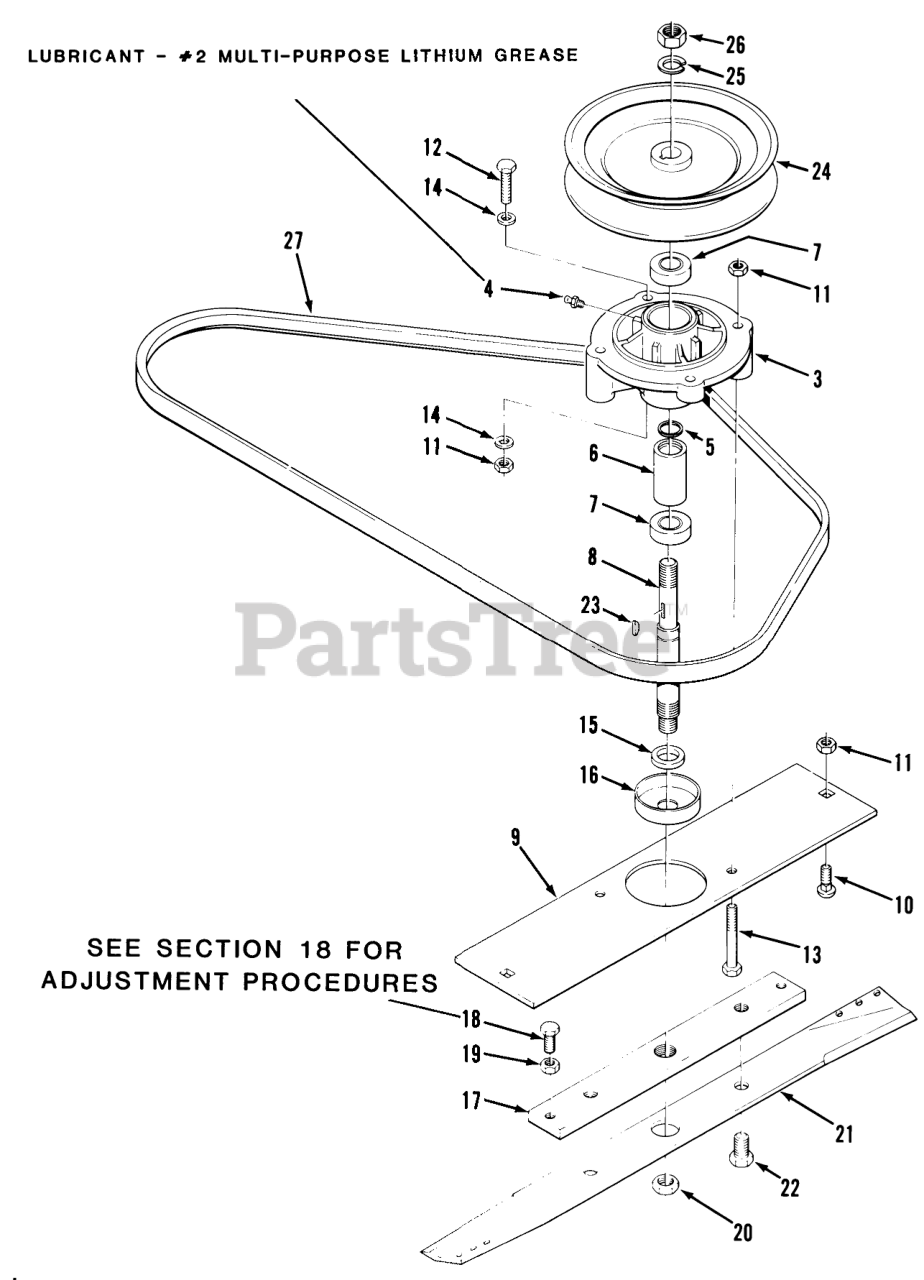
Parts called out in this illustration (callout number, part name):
5	SNAP RING
15	SPACER-BLADE
19	NUT-HEX, JAM
23	KEY-HI-PRO
24	PULLEY HUB ASSY
26	Nut 5/8-18
